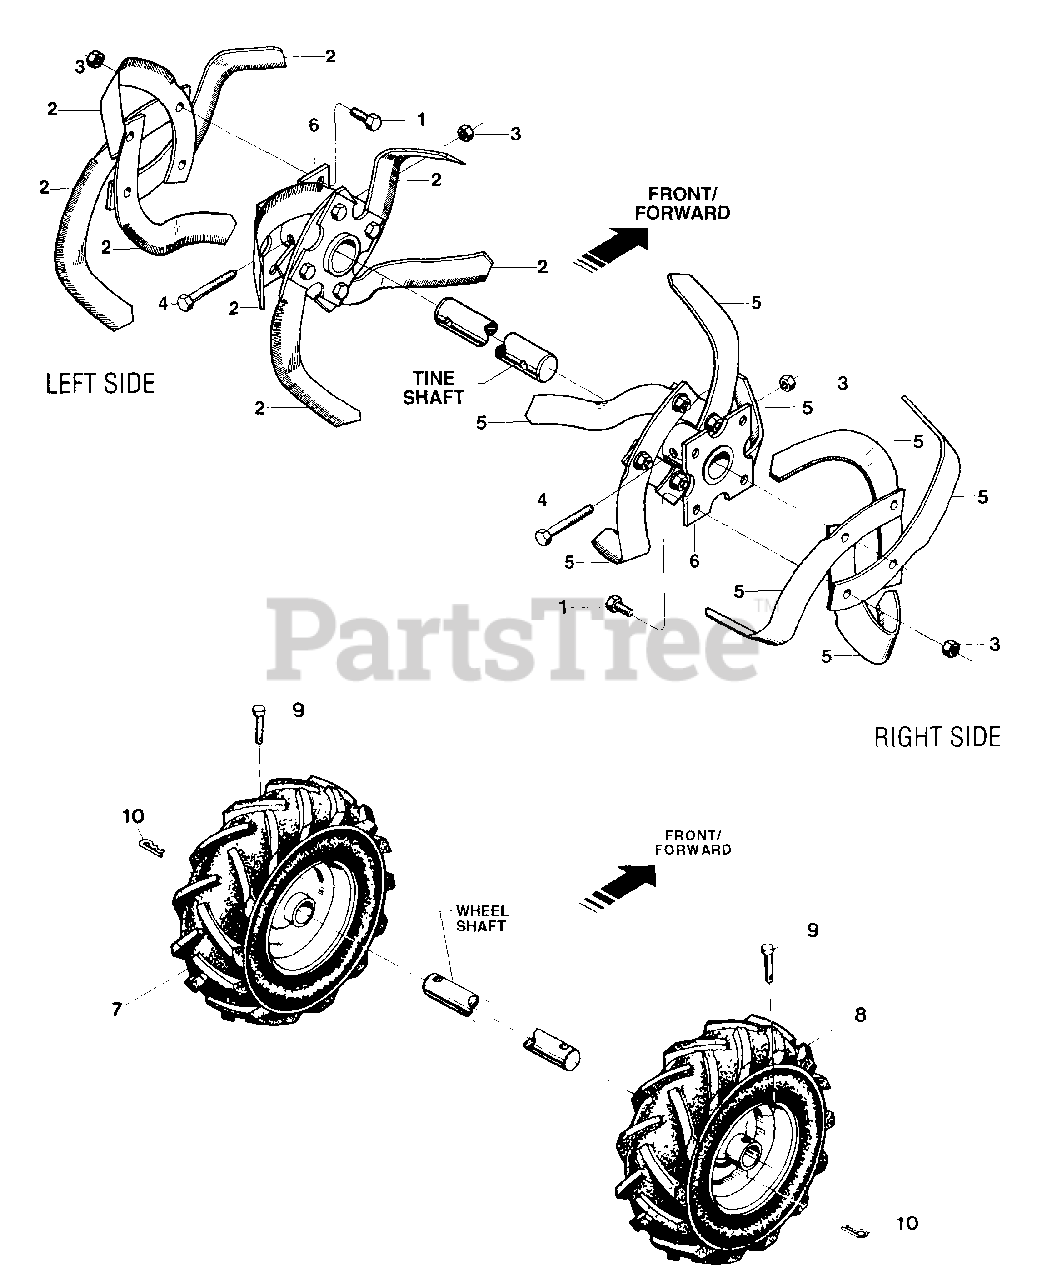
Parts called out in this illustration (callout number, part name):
1	Bolt-Hex Head, 3/8-16 x 1", Grade 5, Tine Mounting
2	Bolo Tine-Single,
3	Locknut-Hex Hd, 3/8-16
4	Bolt-Hex Hd, 3/8-16 x 1-3/4"
5	Bolo Tine-Single
6	Tine Holder
7	Wheel & Tire Assy-Left Side
8	Wheel & Tire Assy-Right Side
9	Clevis Pin .312" x 1-3/4"
10	Hair Pin Cotter
